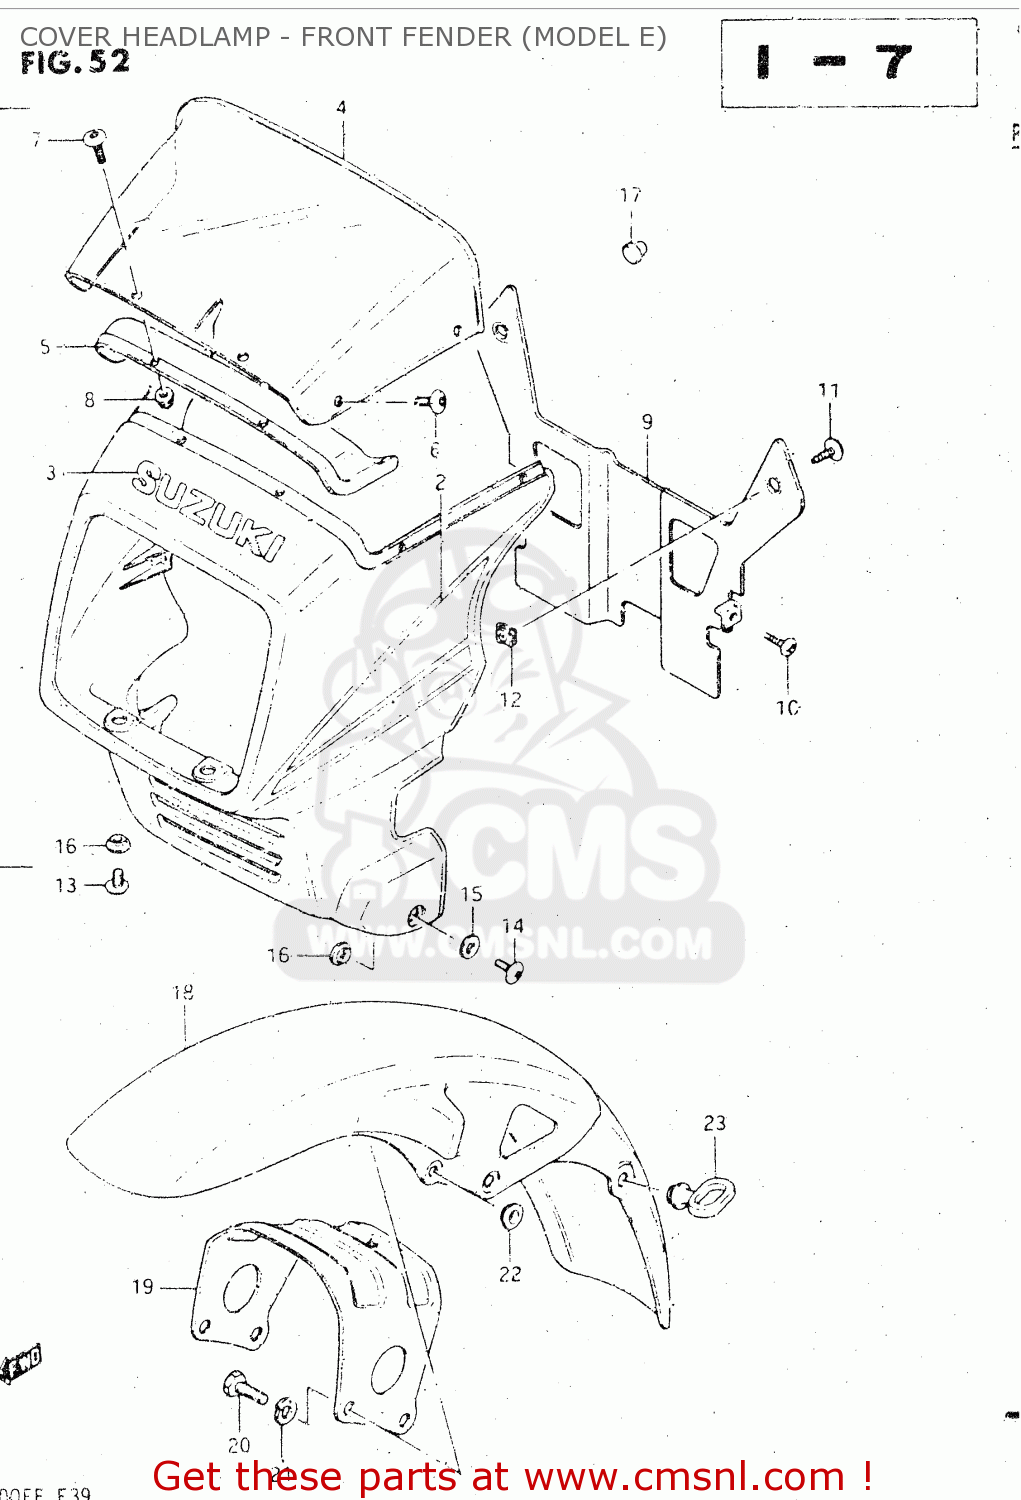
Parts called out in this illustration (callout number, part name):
1	COVER ASSY, HEADLAMP
2	TAPE SET
3	EMBLEM
4	WINDOW,COVER HEADLAMP
5	COVER,HEADLAMP,UPPER
6	SCREW(5X12)
7	SCREW
8	NUT
9	PLATE,HEADLAMP COVER
10	SCREW
11	SCREW
12	NUT
13	SCREW 6X12
14	SCREW 6X12
15	WASHER (6.5X18X1.6)
16	WASHER
17	PLUG
18	FENDER,FRONT
19	BRACE,FRONT FENDER
20	BOLT
21	LOCK WASHER
22	WASHER
23	GUIDE,CABLE
